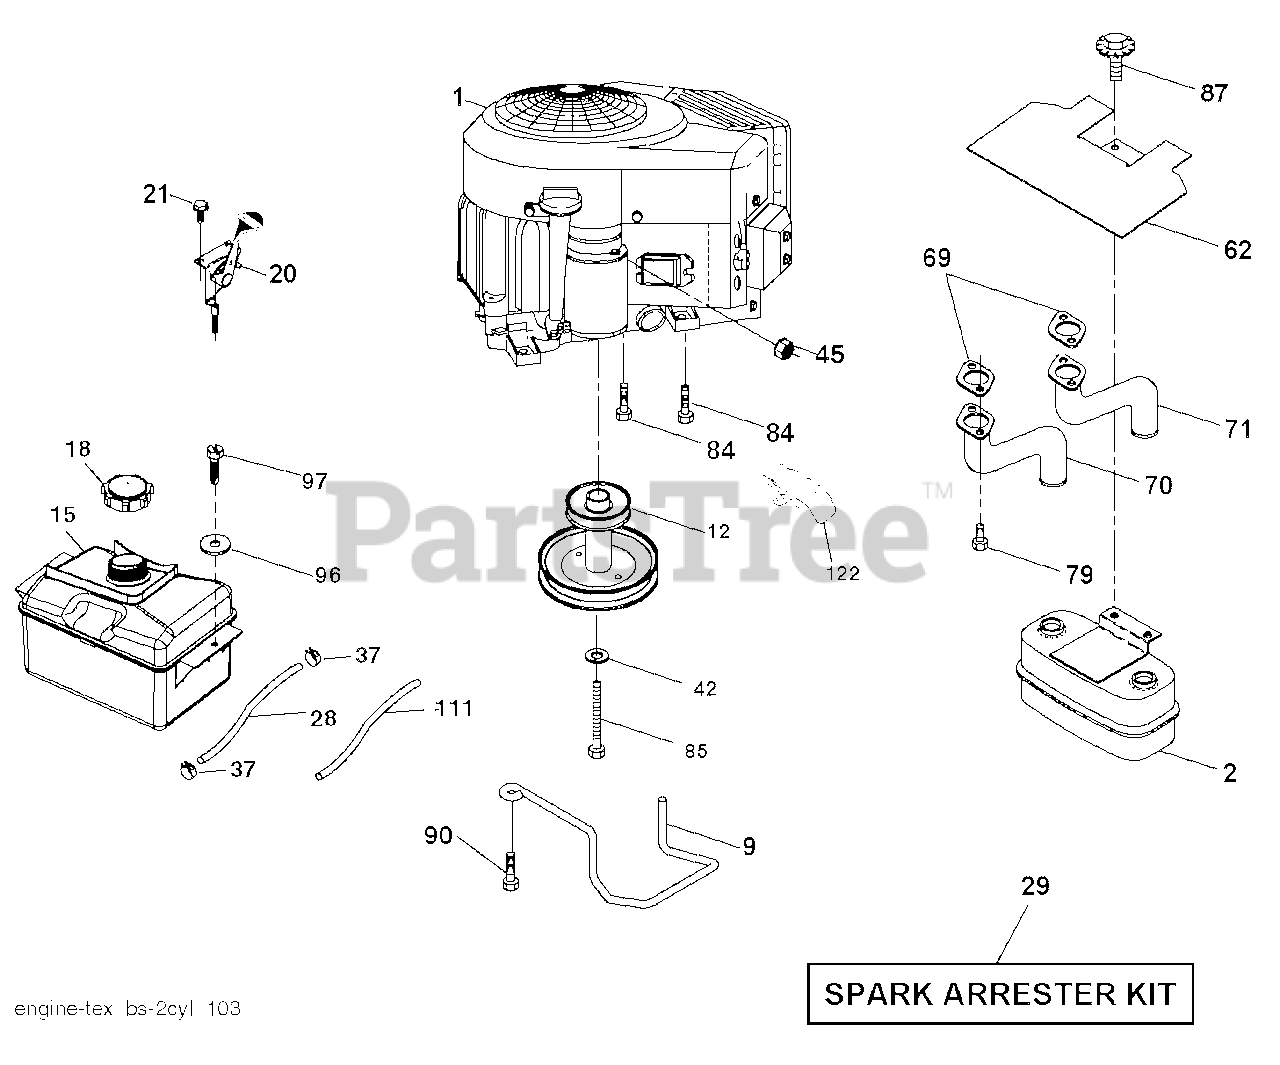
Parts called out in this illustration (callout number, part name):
2	MUFFLER.TWIN.CYL.LOW.TONE
9	KEEPER.BELT.ENGINE.3.25
12	PULLEY.ENGINE.5.0.PD
15	TANK.ASM.FRT.2.5 GAL.W/CAP.EPA
18	CAP.FUEL.2 WAY VENT
20	CONTROL.TH/CK.COBRA.B&S.TWN.
21	SCREW.#10 X 0.750.BOS (2 2)
28	LINE.FUEL.20
29	KIT.SPARK ARRESTOR(392390 B&S)
37	HOSE CLAMP
42	LOCKWASHER
45	NUT
62	SHIELD.HEAT.MUFFLER
70	EXHAUST.TUBE.LH.BS/TWIN
71	EXHAUST.TUBE.RH.B&S.TWIN.INTEK
79	SCREW.SOCKET.HEAD.5/16-18
84	SCREW.3/8-16
85	BOLT HEX 7/16-20X4-1/4"
87	BOLT, 5/16-18 X 1 3/4
90	SCREW 3/8-16X1
96	WASHER
97	SCREW HEXWSHR 1/4-20X3/4
111	RP PURGE LINE
122	EXTENSION DRAIN OIL
